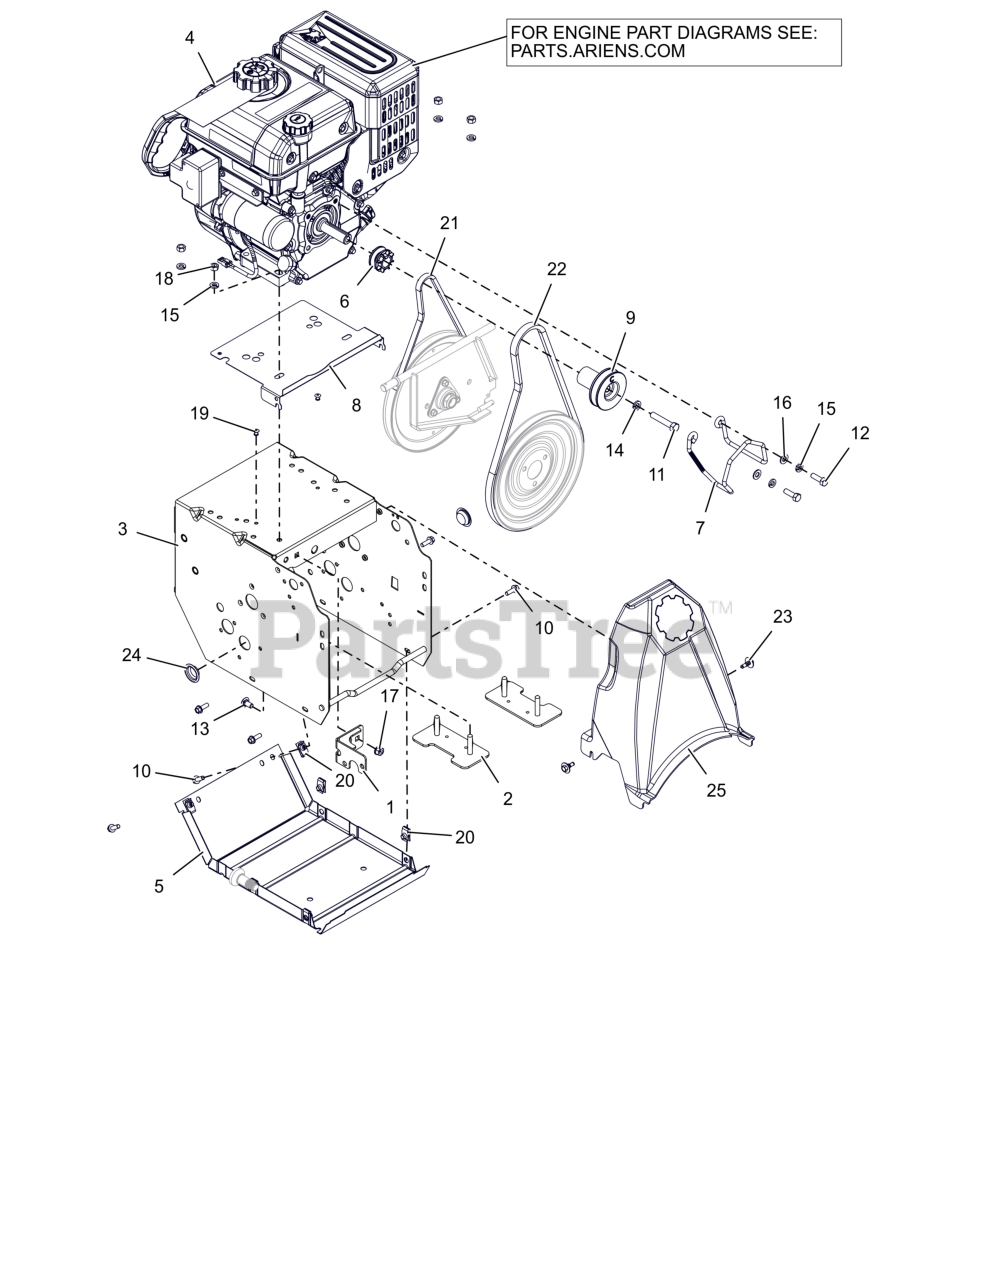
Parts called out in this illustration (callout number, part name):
1	WELDMENT, FRAME BRACKET
2	STRAP, ENGINE BOLT-WELDMENT
3	FRAME, MAIN
4	ENGINE, ARIENS AX224 240V/60W
5	COVER, BOTTOM
6	SHEAVE, TRACTION
7	FINGER, BELT
8	BAFFLE- COMPACT
9	SHEAVE, ATTACHMENT SINGLE GRV
10	BLT, HWH .25-20X.75 G5 ZCC
11	BLT, HEX .38-24X2.00 G5 ZCC
12	BLT, HEX 0.3125-24X1 G5 ZCC
13	BLT, RHSSN .31-18X.625 G5 ZCC
14	WSHR,LK-REG .375X.094 ZCC
15	WSHR, LK-HVY .312X.097 ZCC
16	WSHR,FLT .344X.688X.065 ZCC
17	NUT-LK-TOP-FLG .312-18 GF ZCC
18	NUT, HEX .312-18 ZCC
19	RVT, POP .1875 ZCC
20	NUT-RTNR .25-20X.56
21	V-BELT, 3L-WRAPPED
22	V-BELT, HA-RAW EDGE
23	SCR-TAP .25-20X.5 CAPTIVE
24	PLUG, HOLE - 1.00" FLEXTEMP
25	COVER- CLASSIC BELT
